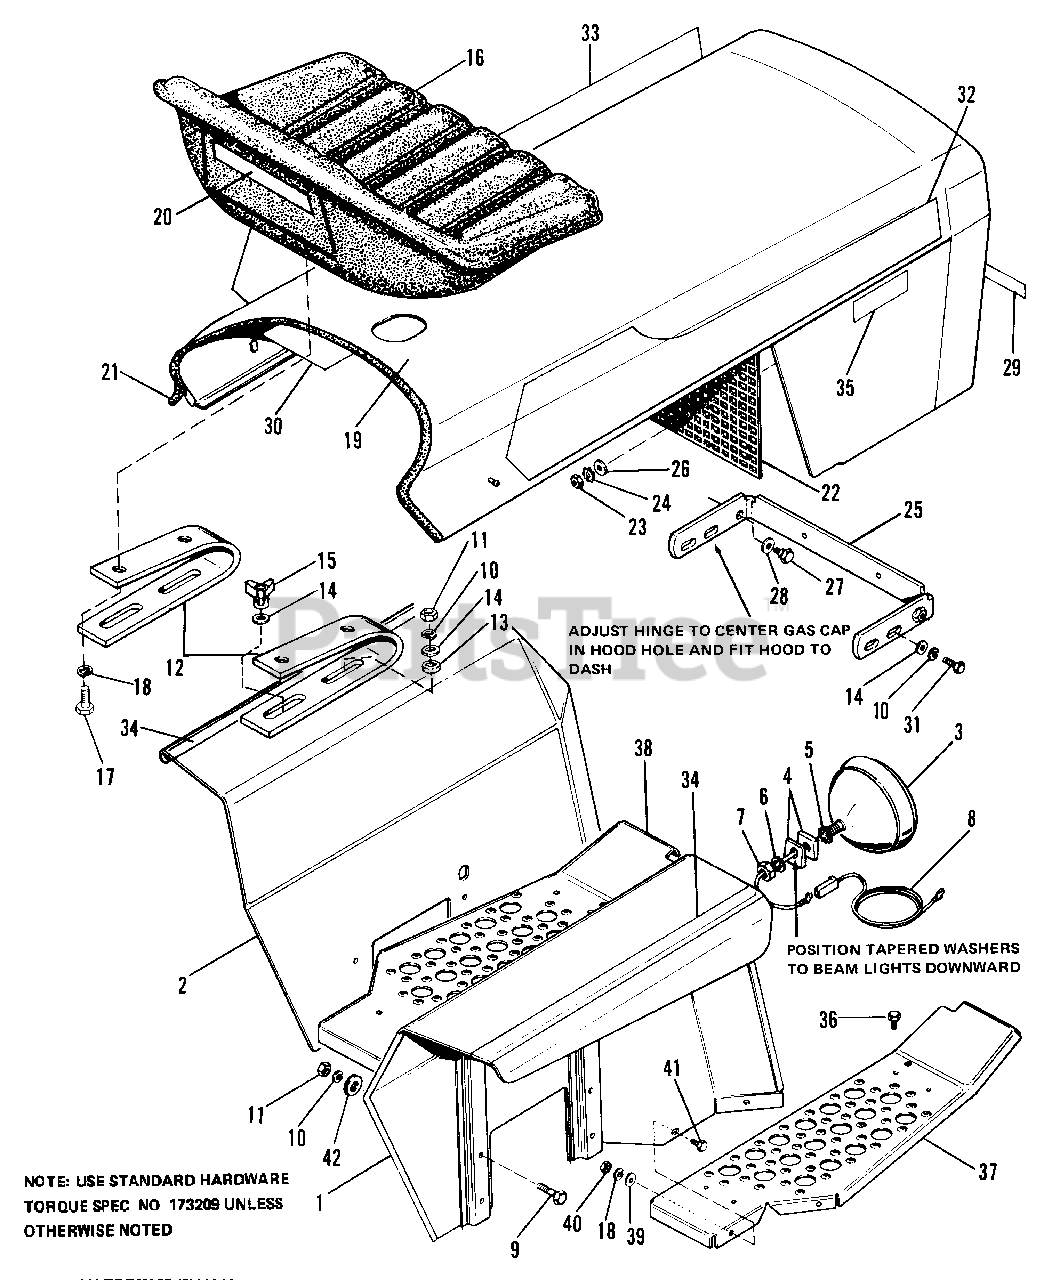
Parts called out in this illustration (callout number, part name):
1	GUARD ASSY, Wheel, R.H.
2	GUARD ASSY, Wheel, L.H.
3	LAMP ASSY
4	WASHER, Special
5	LOCKWASHER, External Tooth, 1/2
6	LOCKWASHER, 1/2
7	NUT, Hex, Jam, 1/2-13
9	CAPSCREW, Hex, 3/8-16 x 1-3/4
10	LOCKWASHER, 3/8
11	NUT, Hex, 3/8-16
12	SPRING, Seat
14	WASHER, Plain, 3/8
15	KNOB, Three Arm
17	CAPSCREW, Hex, 5/16-18 x 3/4
18	LOCKWASHER, 5/16
19	HOOD ASSY
20	DECAL, Simplicity
23	NUT, Hex, No. 10-24
24	LOCKWASHER, Ext. Tooth, No. 10
25	HINGE ASSY
27	BOLT, Shoulder
29	DECAL, Power Lift
30	DECAL, Service
31	CAPCSREW, Hex, 3/8-16 x 3/4
32	DECAL, Hood, R.H.
33	DECAL, Hood, L.H.
34	DECAL, Fender
35	DECAL, 9020
36	SCREW, Tapping, 5/16-18 x 7/8
37	PLATFORM, R.H.
38	PLATFORM, L.H.
39	WASHER, Plain, 1/4
40	NUT, Hex, 5/16-18
41	CAPSCREW, Hex, 5/16-18 x 5/8
42	WASHER, Plain, 13/32 x 1-1/2
